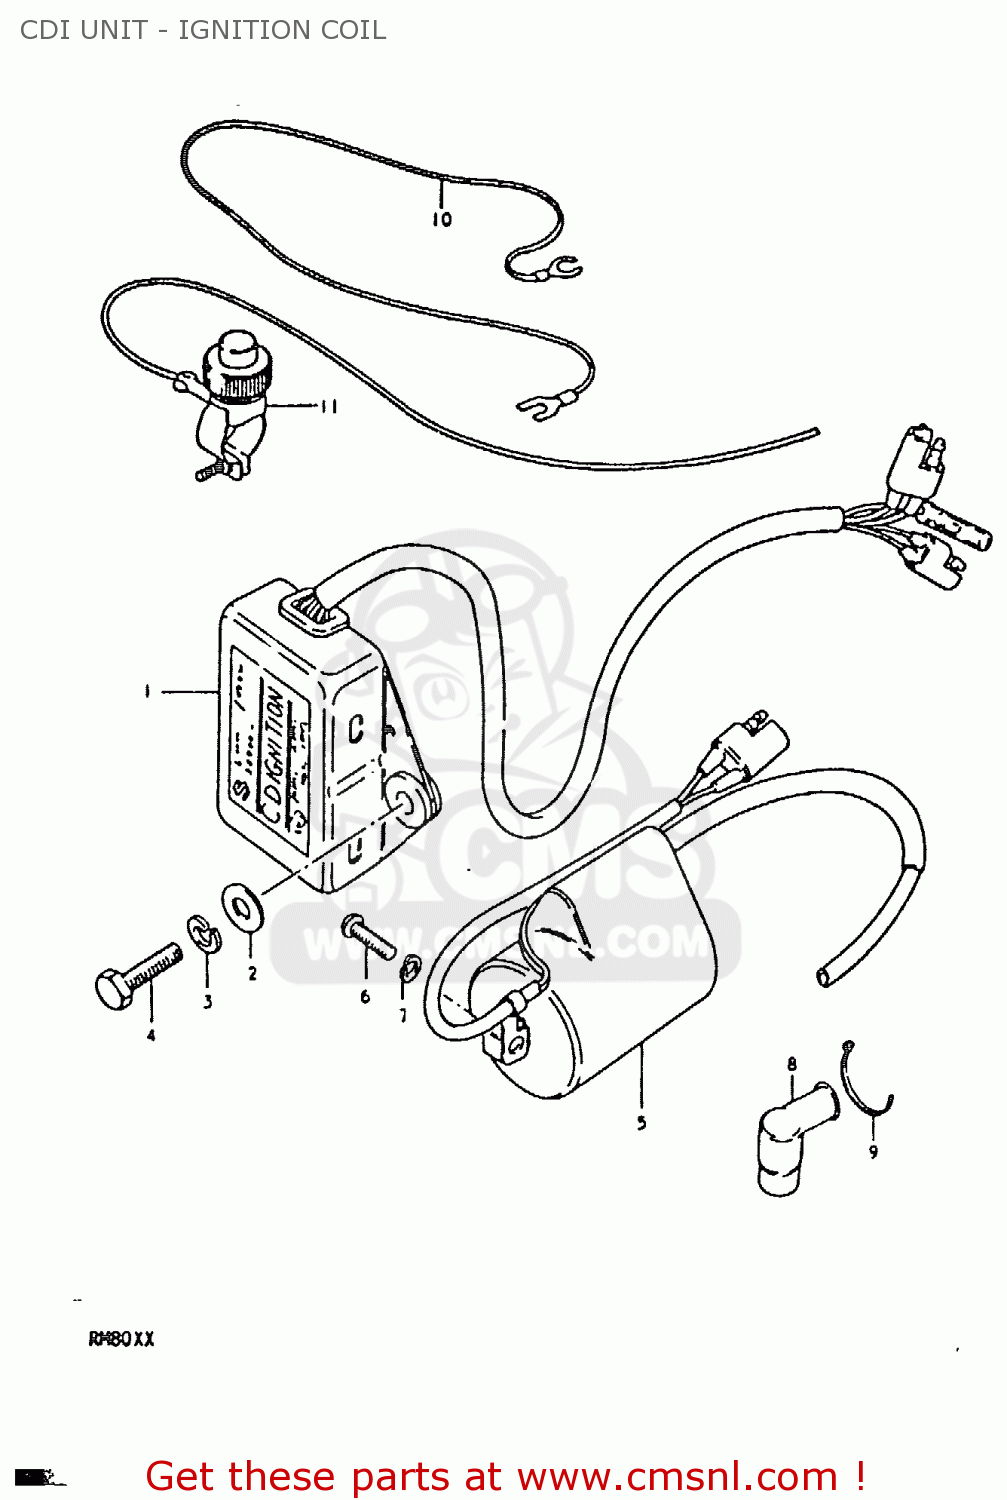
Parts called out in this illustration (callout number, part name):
1	CDI UNIT
2	WASHER(6.5X16X1.2)
3	LOCK WASHER
4	BOLT
5	COIL ASSEMBLY,IGNITION
6	SCREW 5X20
7	LOCK WASHER
8	CAP,SPARK PLUG
9	CLAMP
10	WIRE,ENGINE STOP EARTH
11	SWITCH ASSEMBLY
